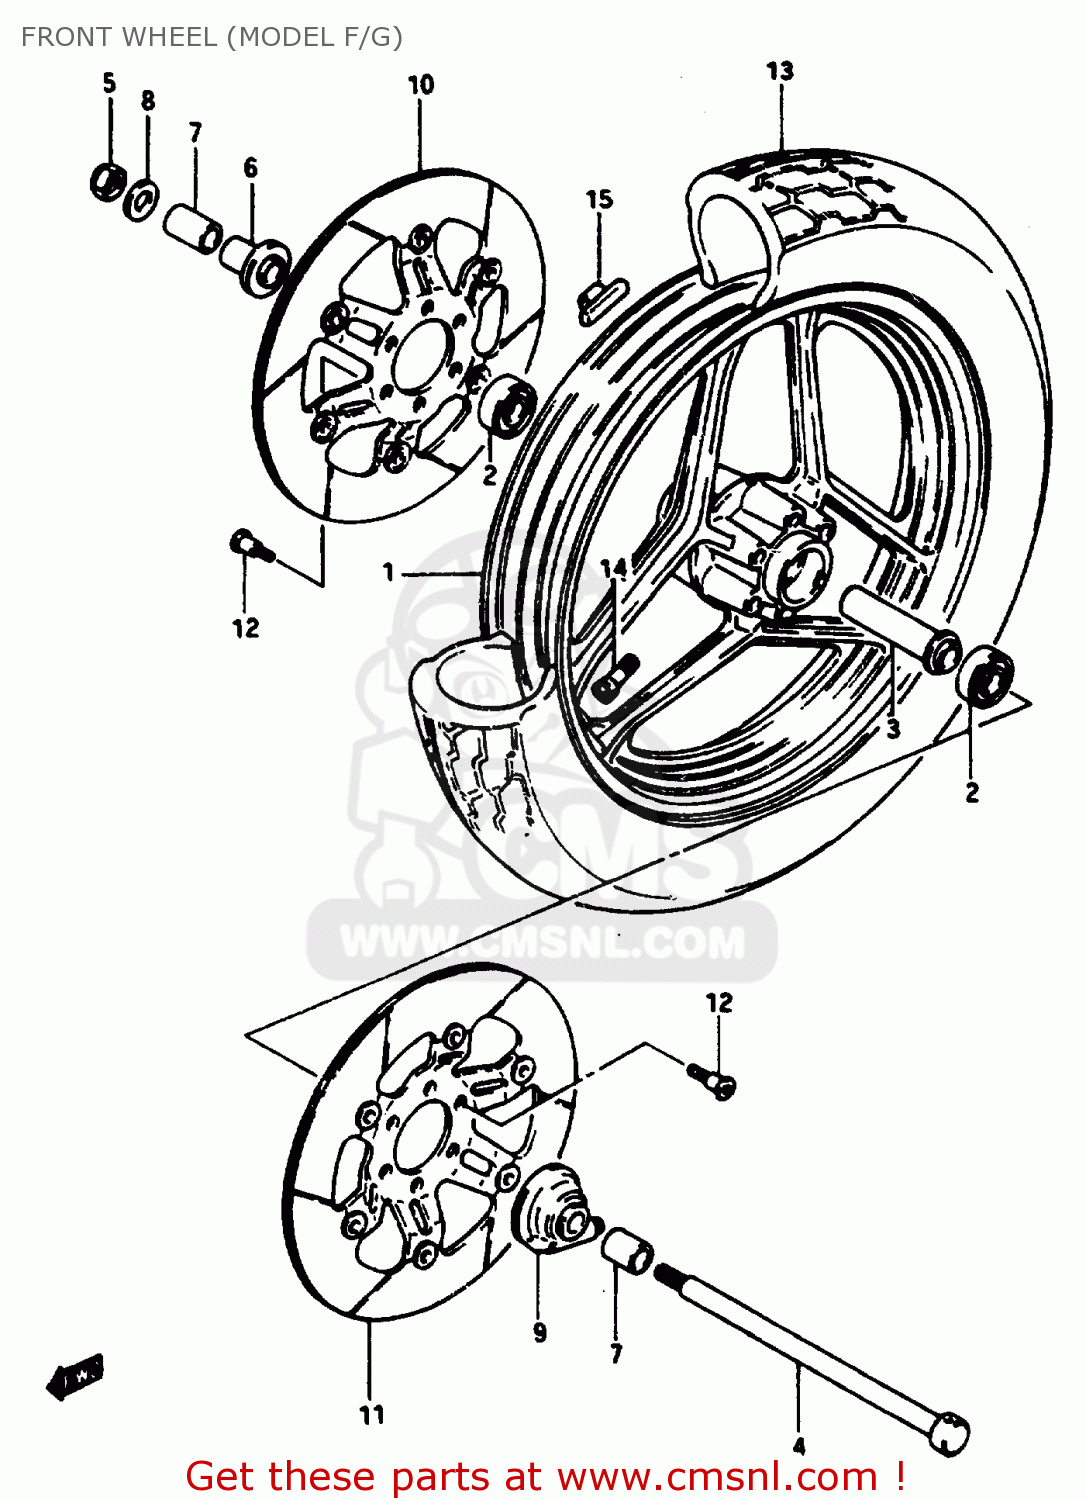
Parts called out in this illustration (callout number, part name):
1	CASTING WHEEL,
2	BEARING
3	SPACER,FRONT HUB BEARING
4	AXLE,FRONT
5	NUT
6	SPACER,FR AXLE,R
7	SPACER(15X22X30)
8	WASHER
9	BOX ASSY,SPEEDOMETER GEAR
10	DISC,FRONT BRAKE,RIGHT
11	DISC,FRONT BRAKE,LEFT
12	BOLT
13	TIRE 110/90-16 (T/L)
14	VALVE,TIRE
15	BALANCER,WHEEL
